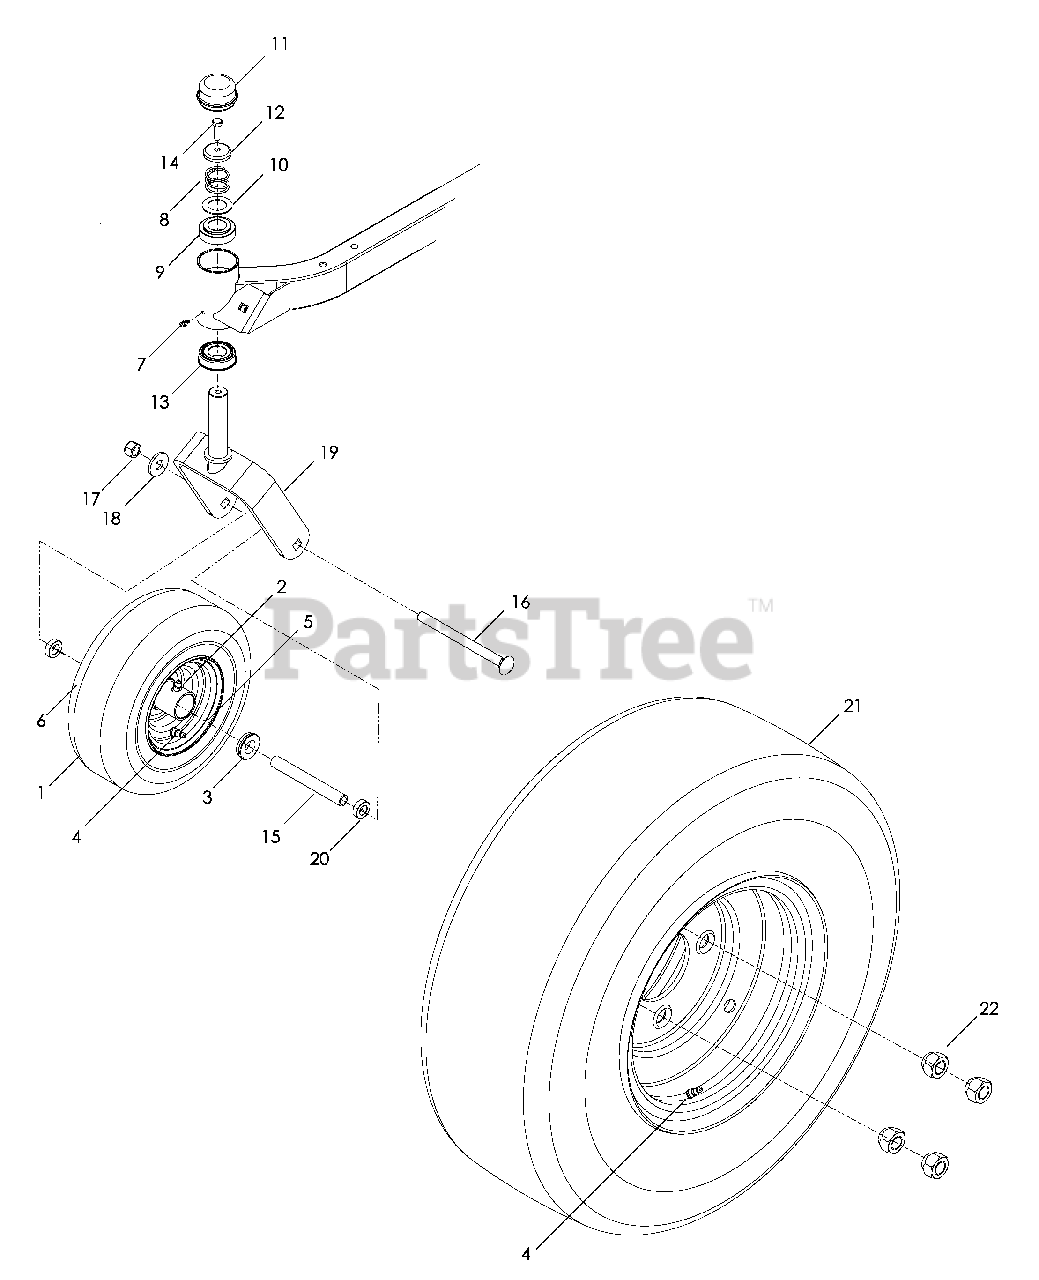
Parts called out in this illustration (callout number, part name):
1	CASTER TIRE ASSM Items 2-6
2	ZERK
3	BEARING, FLANGED
4	VALVE
6	TIRE
7	ZERK
8	SPRING, CASTER
9	BUSHING, CASTER
10	WASHER
11	CAP, GREASE
12	PLUG, CASTER
13	BEARING, FLANGED
14	HHB 5/16-18 x 1 NYLOC
15	SPACER
16	RHSNB ½-13 x 6½
17	NUT ½ HEX NYLOC
18	WASHER ½ FLAT
19	YOKE, CASTER
20	SPACER 5/16
21	WHEEL ASSM REAR
22	NUT ½ LUG
